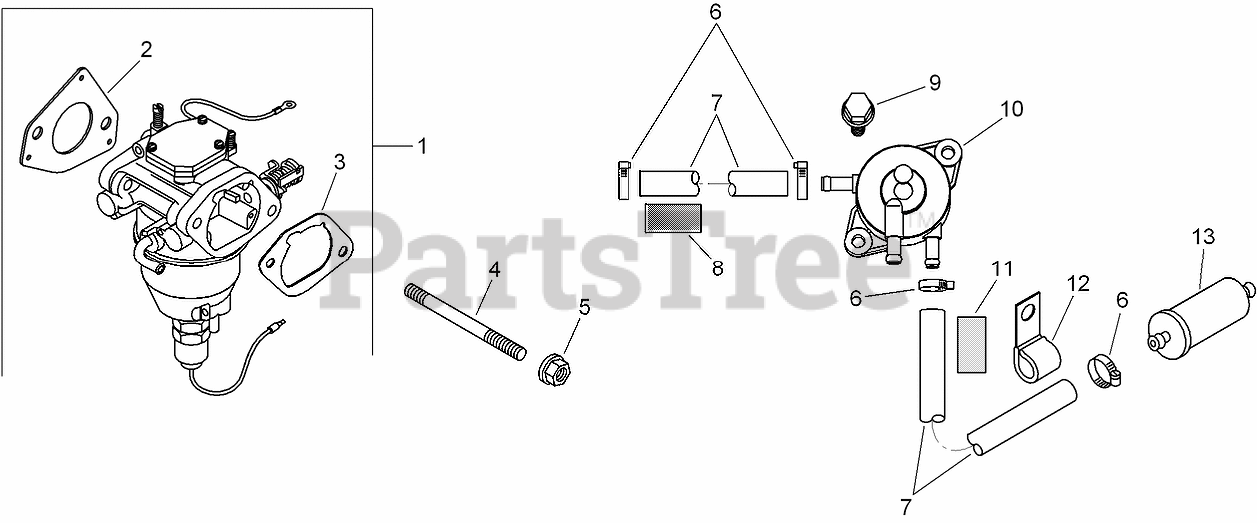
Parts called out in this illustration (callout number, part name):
1	CARBURETOR KIT-22mm KEIHIN (INCLUDES 2, 3)
2	GASKET-CARBURETOR
3	GASKET-BASE, AIR CLEANER
4	STUD (M6X1.0X106)
5	NUT-FLANGE (M6X1.0)
6	CLAMP-HOSE, SPRING (1/2)
7	LINE-FUEL (24.0 CUT TO LENGTH)
8	SLEEVE-ABRASION, ANTI
9	SCREW-TAP (M6X1.7X18)
10	PUMP-FUEL
11	SLEEVE-ABRASION, ANTI
12	CLIP-CABLE
13	FILTER-FUEL
